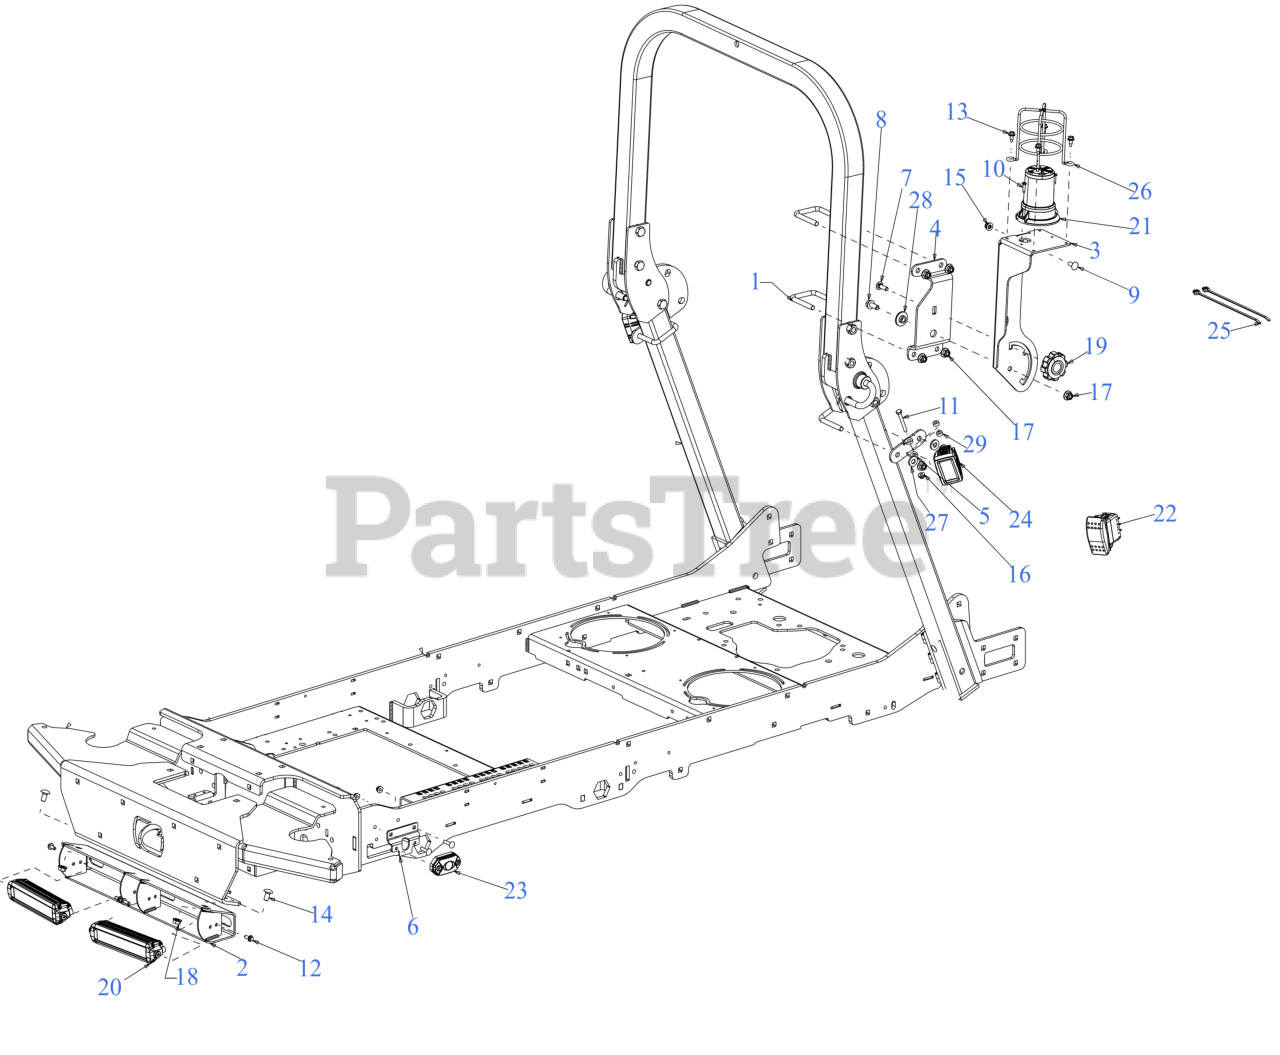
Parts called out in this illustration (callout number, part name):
1	U-BOLT, 3/8-16 X
2	HEADLIGHT BRACKET
3	PIVOT MOUNT BRACKET
4	FIXED MOUNT BRACKET
5	LIGHT MOUNT BRACKET
6	BRACKET
7	CARRIAGE BOLT 5/16-18 x 1.00
8	SCREW 3/8-16 x .875 GR5
9	CARRIAGE BOLT 5/16-18 x .75
10	SCREW (10-24X.75:PH:TAP:T25:GR5)
11	SCREW 1/4-20 x 2 GR5
12	SCREW M6-1 x .625
13	SCREW 1/4-20X.625
14	CARRIAGE BOLT 3/8-16 x .75
15	FLANGE LOCK NUT 5/16-18
16	FLANGE LOCK NUT
18	HEX LOCK NUT
19	KNOB-5/16-18
20	LED HEADLIGHT (2000LM)
21	LED BEACON LIGHT
22	ROCKER SWITCH
23	LED HEADLIGHT (300LM)
24	LED HEADLIGHT (400LM)
25	CABLE TIE
26	BEACON LIGHT COVER
27	FLAT WASHER
28	SHOULDER SPACER
